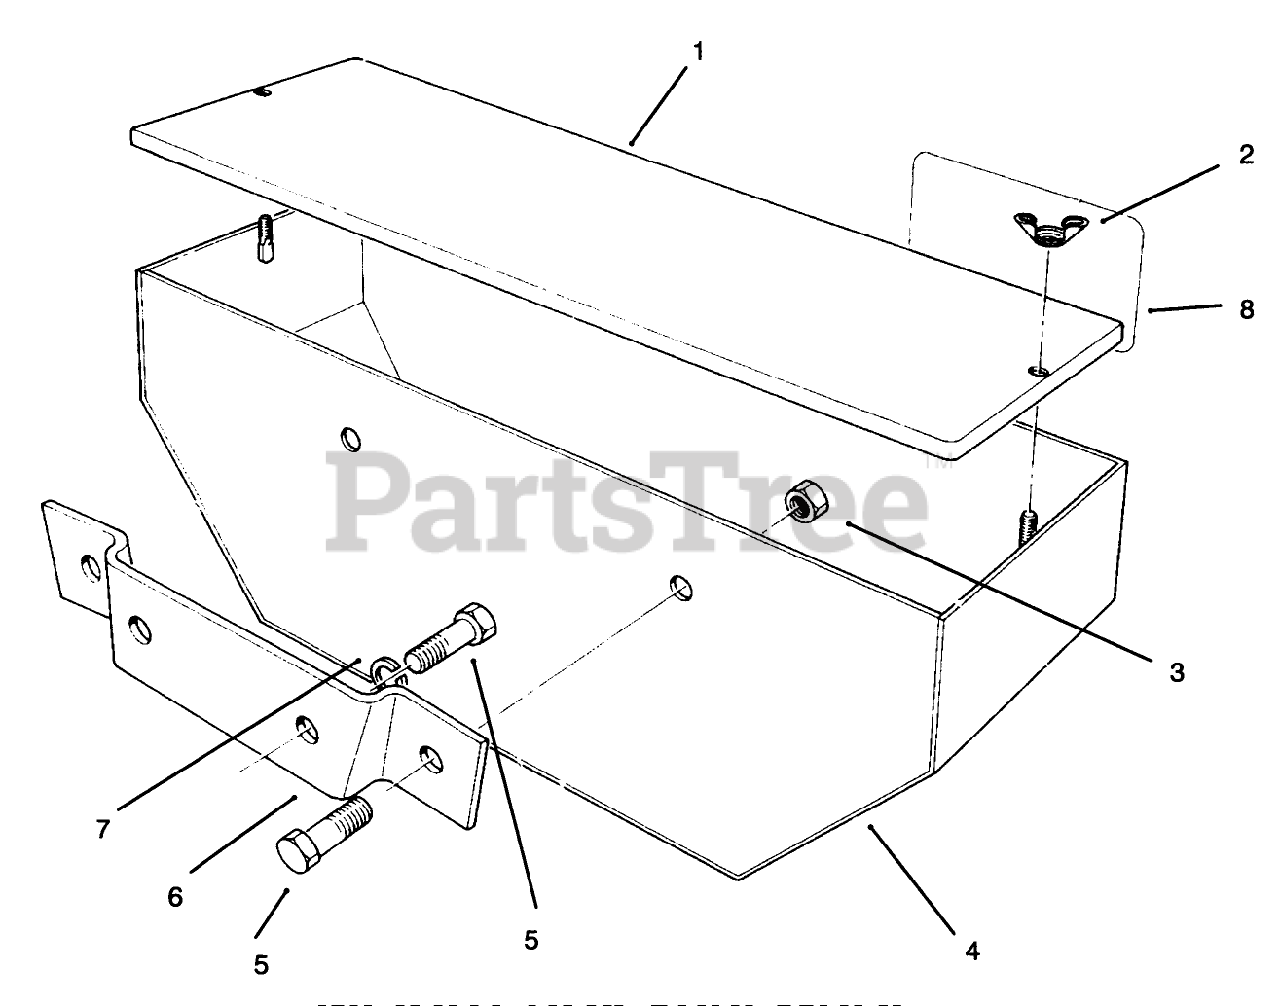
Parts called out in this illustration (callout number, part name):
1	WT BOX COVER R
2	NUT-WING
3	NUT-LOCK, NI
4	WEIGHT BOX WA
5	SCREW-HH
6	MOUNT BRKT R
7	WASHER-LOCK
8	DECAL
